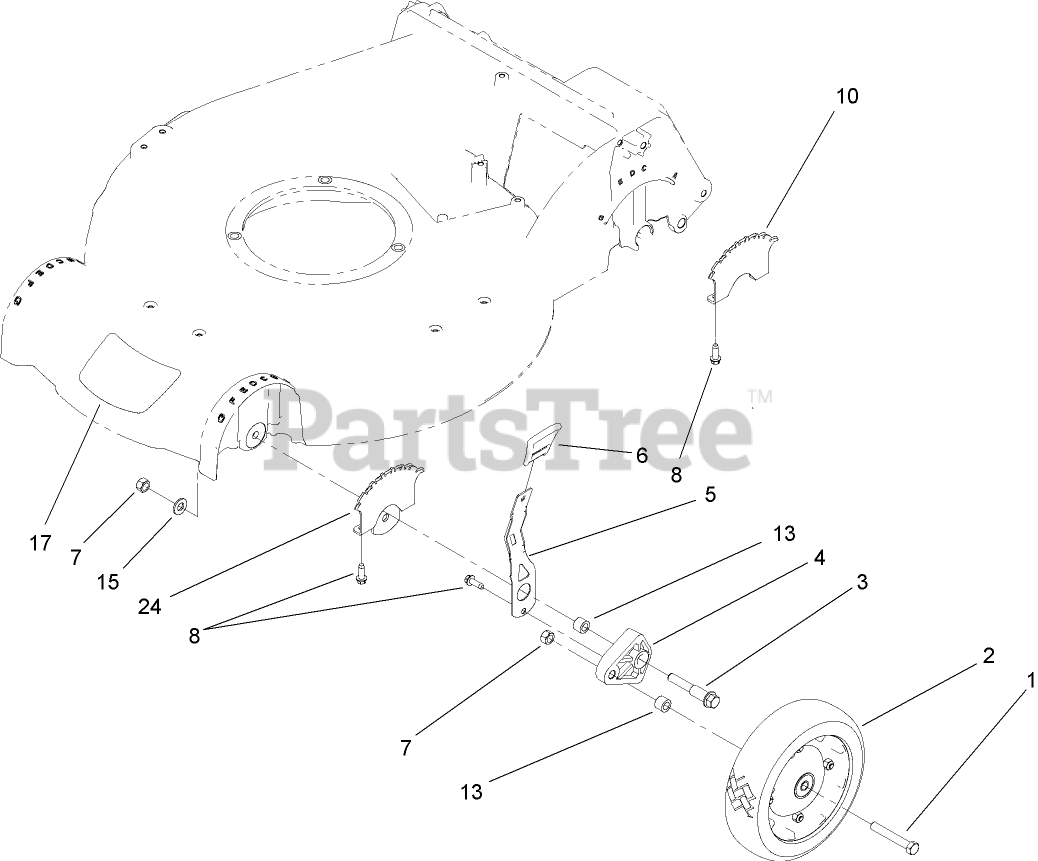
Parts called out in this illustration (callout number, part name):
1	SCREW-HH
3	SCREW-SHOULDER
4	ARM-PIVOT
5	ARM-SPRING
6	KNOB-HOC
7	LOCKNUT
8	SCREW-HWHTF
10	PLATE-HOC
13	SPACER-WHEEL
15	WASHER-FLAT
17	DECAL-LOGO
24	BRACKET-SUPPORT
